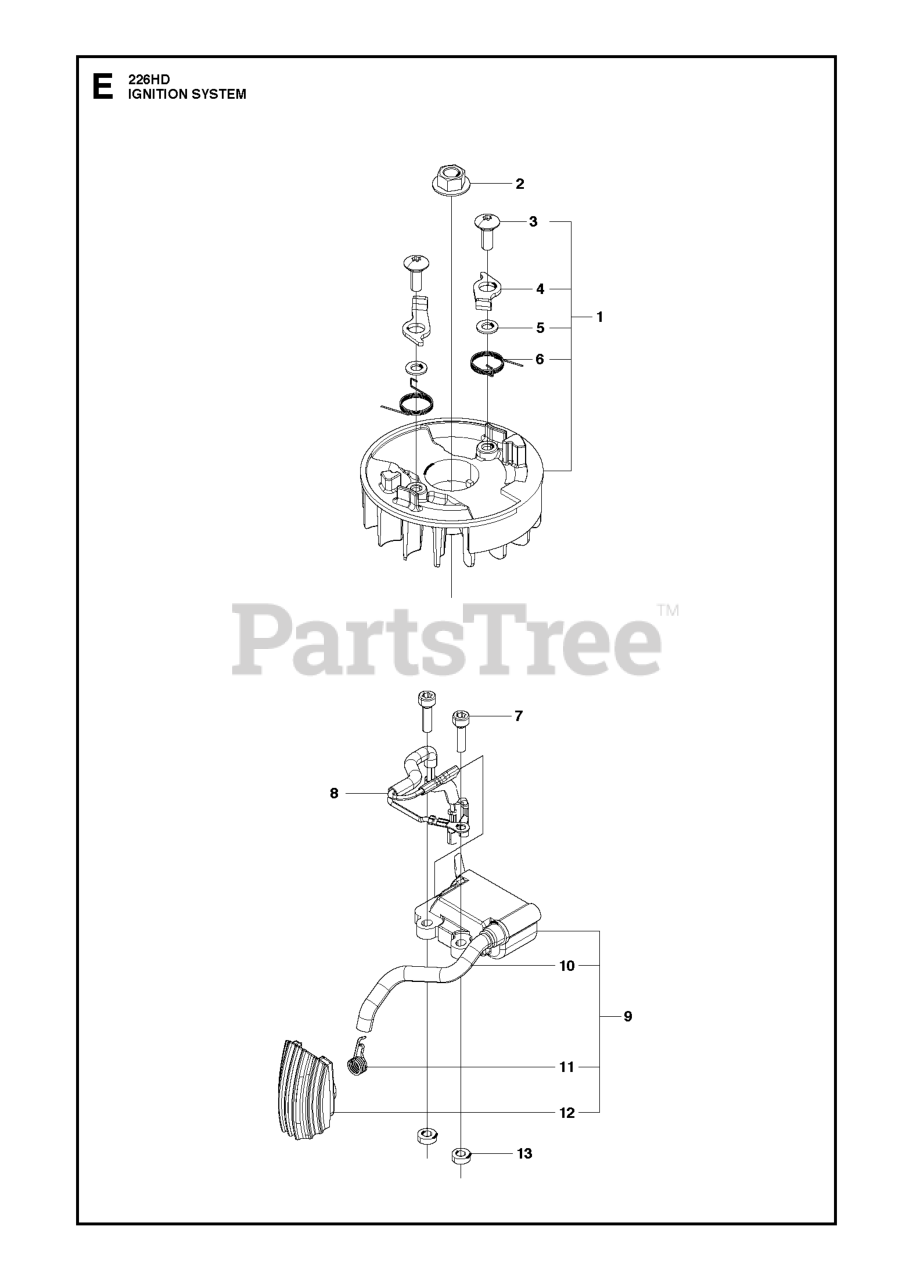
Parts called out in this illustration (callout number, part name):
1	ROTOR ASSY
2	NUT
5	WASHER 5X10X10
9	COIL ASSY
